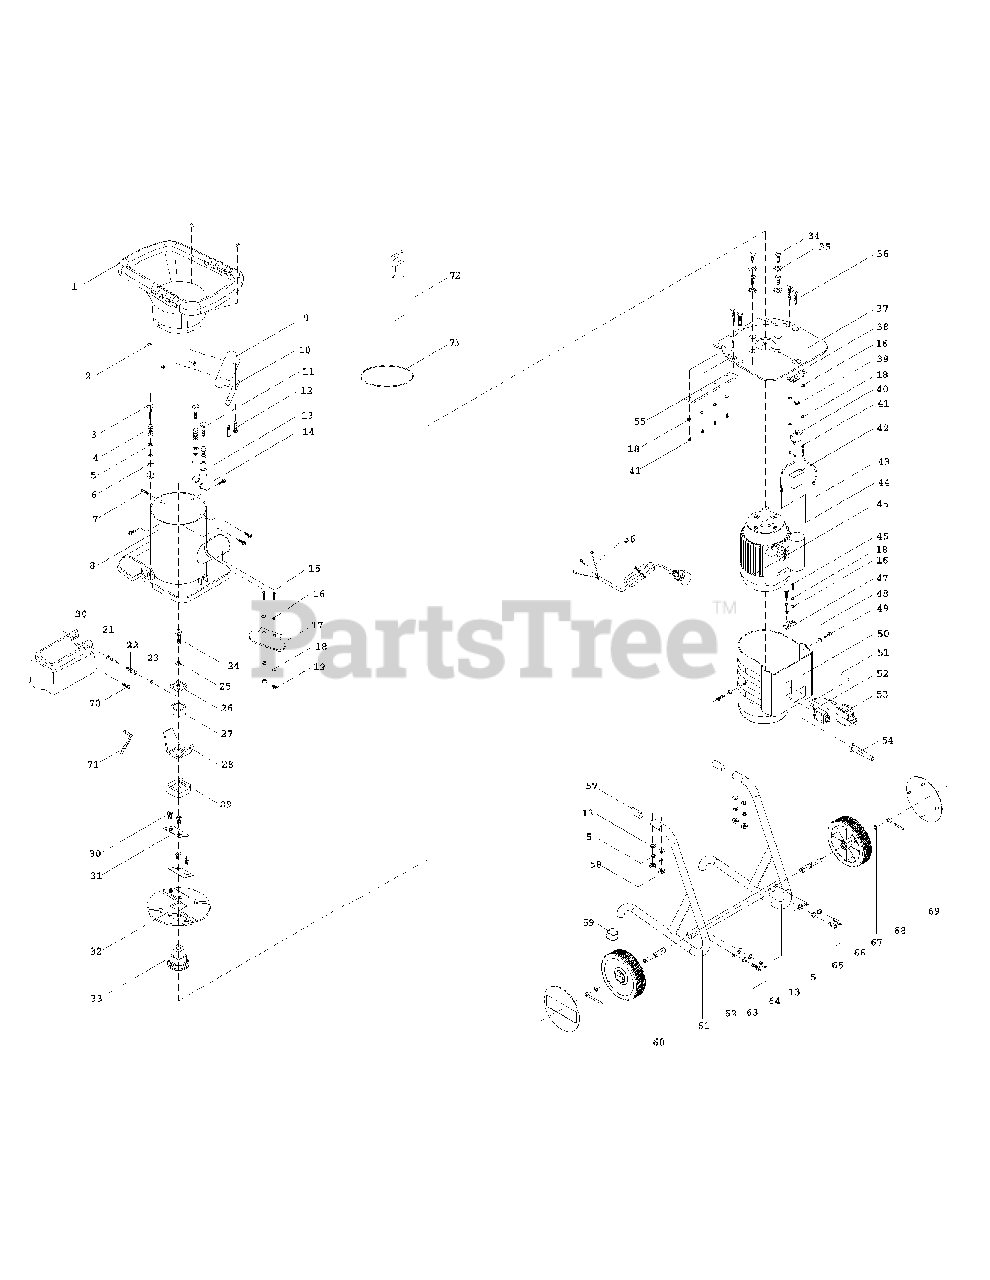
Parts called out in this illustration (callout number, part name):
1	TOP HOPPER
4	RESTRAINNIG SPRING
5	SPRING WASHER
9	DUST PLATE
10	CUTTER CLAMP
14	E RING
17	DUST PLATE
19	SPRING WASHER
20	RESTRAINING COVER
22	BRACKET TUBE
25	SPRING WASHER
26	CUTTER CLAMP
27	SQUARE BUSH
29	V-CUTTER BASE
30	SCREW M10x10
31	CUTTER (BLADE)
32	CUTTER BASE
33	CUTTER BUSH
34	SCREW M8x18
35	SPRING WASHER
37	BRACKET CLAMP
38	SWITCH HOLDER
39	SWITCH COVER
40	CUT-OUT SWITCH
42	SWITCH COVER
43	INTERNAL WIRE I
44	INTERNAL WIRE II
45	MOTOR ASS'Y
47	CORD CLAMP
50	MOTOR COVER
51	INTERNAL WIRE
52	THERMOSTAT
53	ON/OFF SWITCH
54	CORD GUARD
56	POWER CORD
57	STRENGTEN SHAFT
58	NUT
59	FRAME GASKET
60	WHEEL SHAFT
61	LEFT HOLDER
62	CONNECTING TUBE
64	RIGHT HOLDER
69	WHEEL COVER
72	MARTERIAL PUSH STICK
73	STARP BAG HOLD
